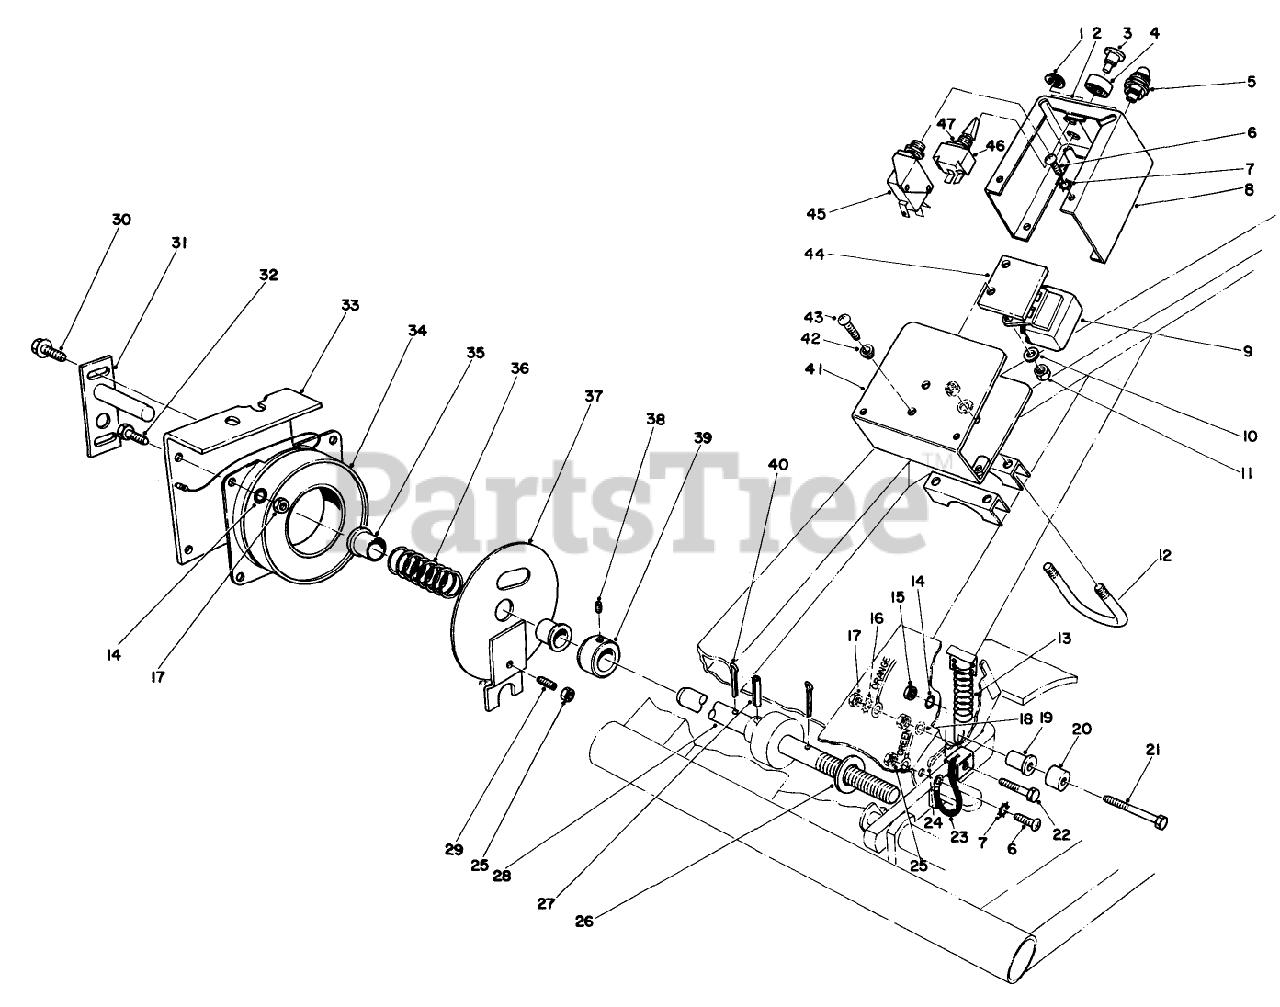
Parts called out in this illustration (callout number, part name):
1	NUT-BULB
2	SPEED CONTROL DECAL
3	BUTTON-PUSH
4	BEZEL
5	Light-Warning
6	SCREW-PPH
7	WASHER-LOCK/EXT
8	Cover-Box
9	Switch-Relay
10	WASHER-FLAT
11	NUT-LOCK, NI
12	MUFFLER CLAMP
13	Extension Spring Assembly
14	WASHER-LOCK
15	NUT-JAM
16	WASHER-LOCK/EXT
17	NUT-HEX
18	WASHER-FLAT
19	NUT-INSERT
20	CONTACT SPACER
21	SCREW-HH
22	SCREW-HH
23	Grounding Clip Assy (w/wire)
24	PIN-COTTER
25	NUT-HEX
26	SPACER
27	PIN-SPRING
28	TRACTION PEDAL SHAFT
29	SCREW-HSH
30	SCREW-HHF
31	Shaft
32	SCREW-HH
33	BRACKET R
34	CORE-FIELD, COIL
35	BUSHING-FLANGE
36	SPRING-COMPRESSION
37	Clutch Plate
38	SCREW-HSH
39	Collar (Incl. Ref. #38)
40	PIN-COTTER
41	Housing
42	INSULATOR SCREW
43	10-24 X 5/8 PAN HD MS
44	Pad-Relay Mounting
45	Switch
46	Switch-Light (Incl. Ref. #1 & 47)
47	NUT-LOCK
